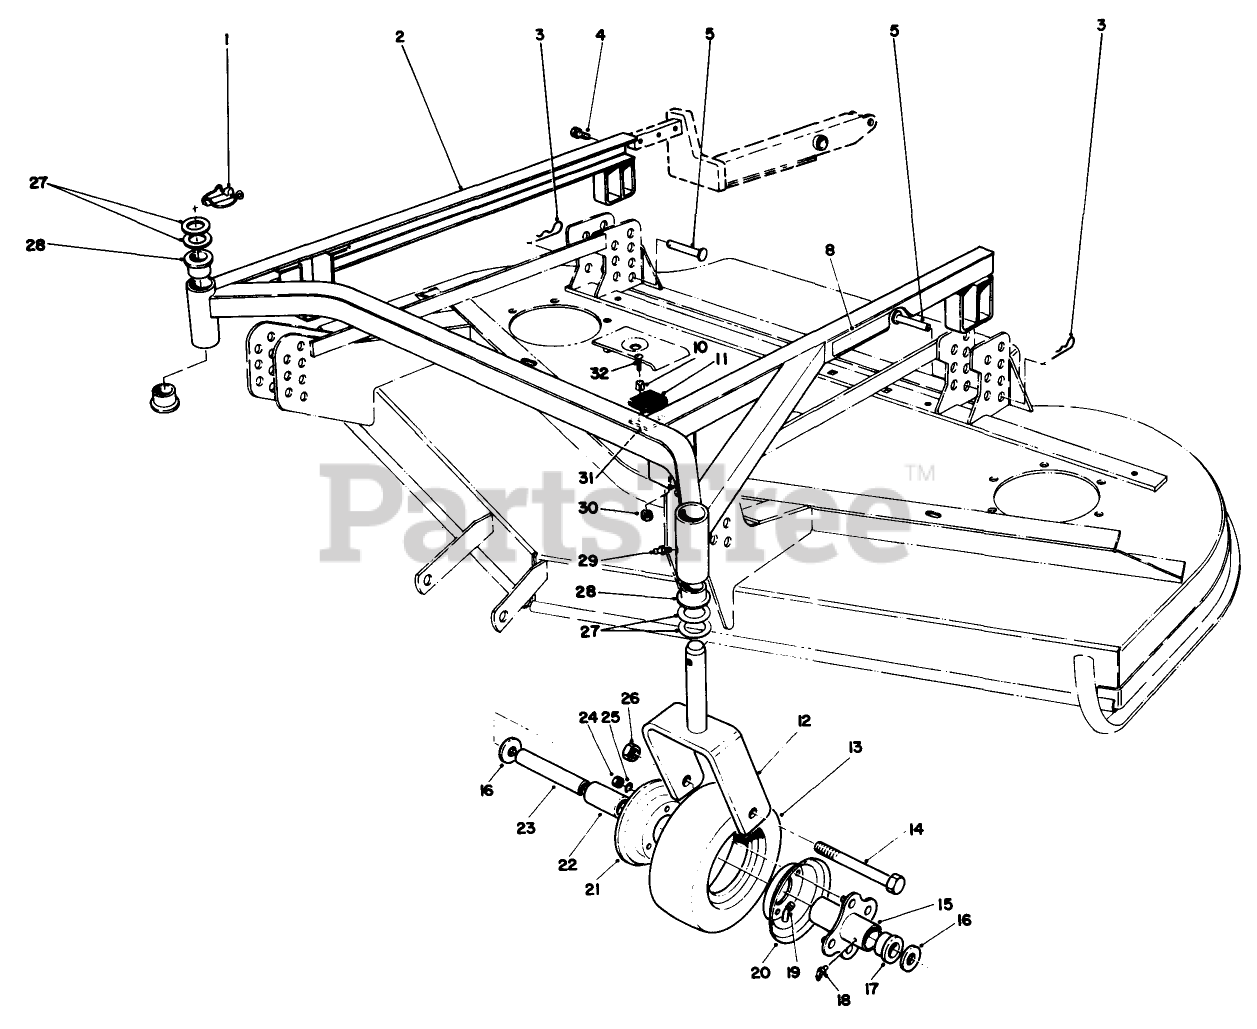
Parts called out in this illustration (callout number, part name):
1	PIN-LYNCH
2	Assembly-Frame, Deck (Incl. Ref. #28)
3	PIN-HAIR
4	SCREW-HH
5	PIN-CLEVIS
8	DECAL - HEIGHT-OF-CUT
10	SPACER
11	CUSHION-RUBBER
12	Castor Fork
14	SCREW-HH
15	HUB-CENTER
16	WASHER-FLAT
17	BEARING-OUTSIDE
18	FITTING-GREASE
19	TUBE-INNER (W/VALVE)
20	FEMALE WHEEL HALF
21	MALE WHEEL HALF
22	BEARING-ROLLER
23	SPANNER-TIRE
24	NUT-HEX
25	WASHER-LOCK
26	NUT-HEX
27	WASHER-THRUST
28	Bushing
29	FITTING-GREASE
30	NUT-LOCK, NI
31	SHIM-CUSHION
